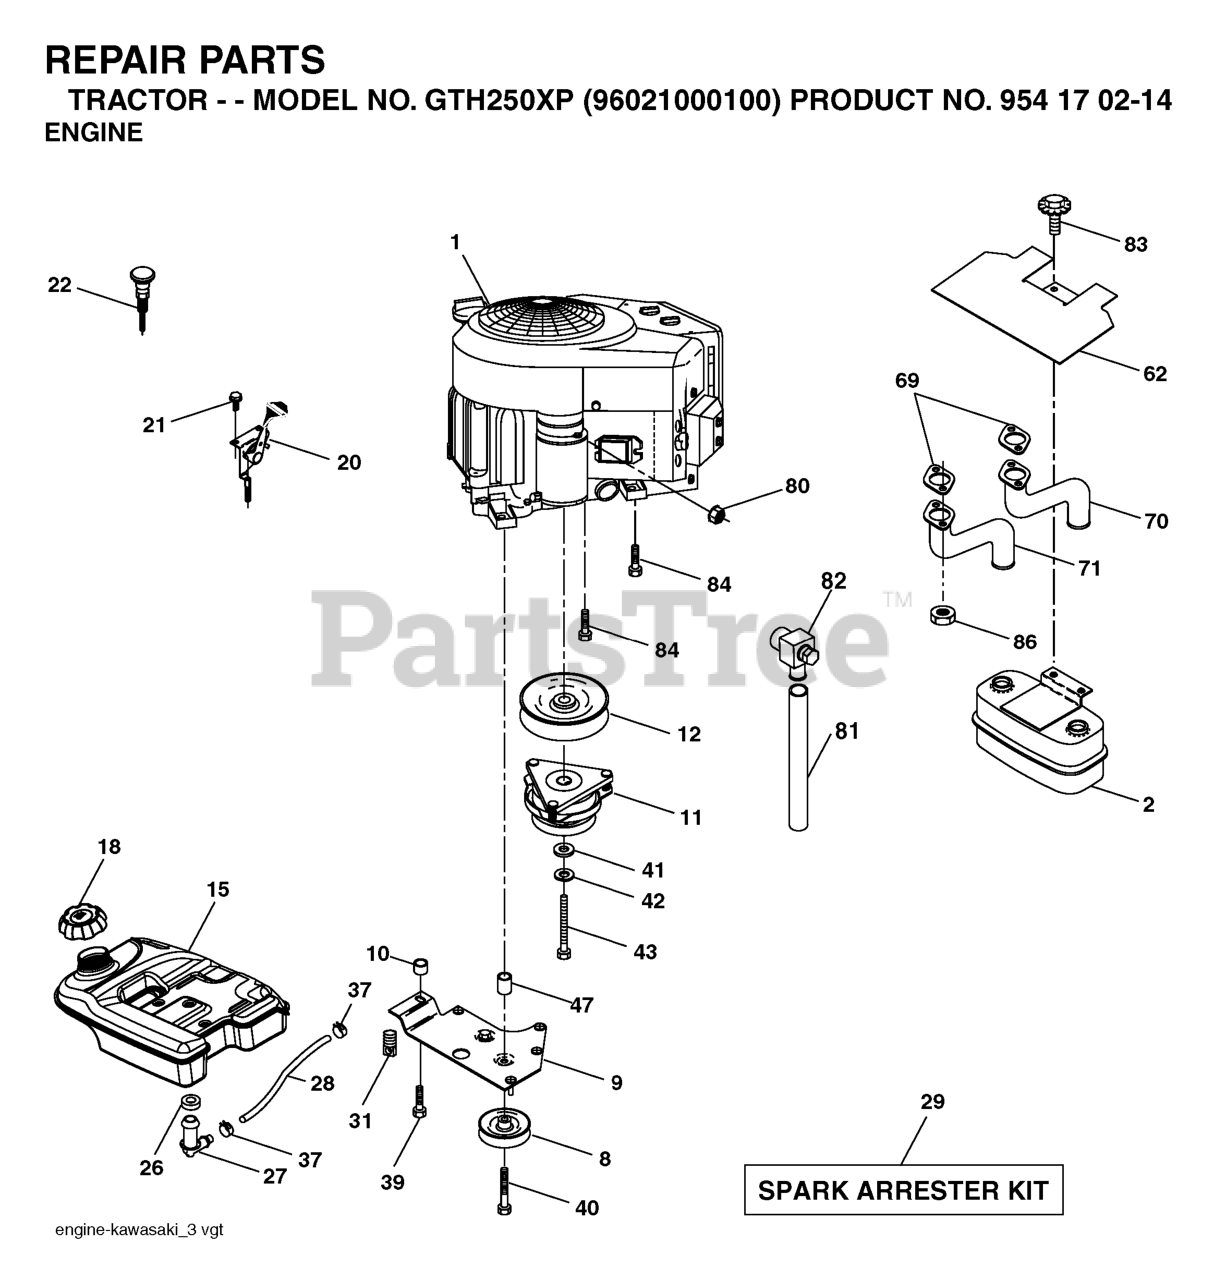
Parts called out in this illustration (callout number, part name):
2	MUFFLER.TWIN.CYL.LOW.TONE
8	RP.IDLER GROOVED
9	KEEPER ASM BELT ENGINE
11	CLUTCH MZ ZTR GT.48/54"1.125"
12	PULLEY ENG VGT ELECT CLUTCH
15	TANK.FUEL.5.0 LEFT.FILL.YTGT
18	TANK CAP
20	CONTROL.THROTTLE.COBRA.42"BLK.
21	SCREW
22	CONTROL, CHOKE
26	BUSHING OUTLET T
27	STEM FUEL TANK
28	HOSE
29	KIT.SPARK ARRESTOR 794945 B&S
37	HOSE CLAMP
39	SCREW TT 3/8-16X2-1/4 UNC
40	Screw TT 3/8-16 x 4 unc
42	LOCKWASHER
43	BOLT HEX 7/16-20 X 3.75 GR. 5
62	HEAT SHIELD
70	TUBE.EXHAUST.KAWASAKI.RH
71	TUBE EXHAUST LH
80	FLANGE NUT
81	TUBE, DRAIN OIL ASM.
83	BOLT.5/16-18UNCX3/4 W/SEMS.BLK
84	SCREW 3/8-16 X 1-1/2
86	NUT.HEX.FLANGE.TOPLOCK
